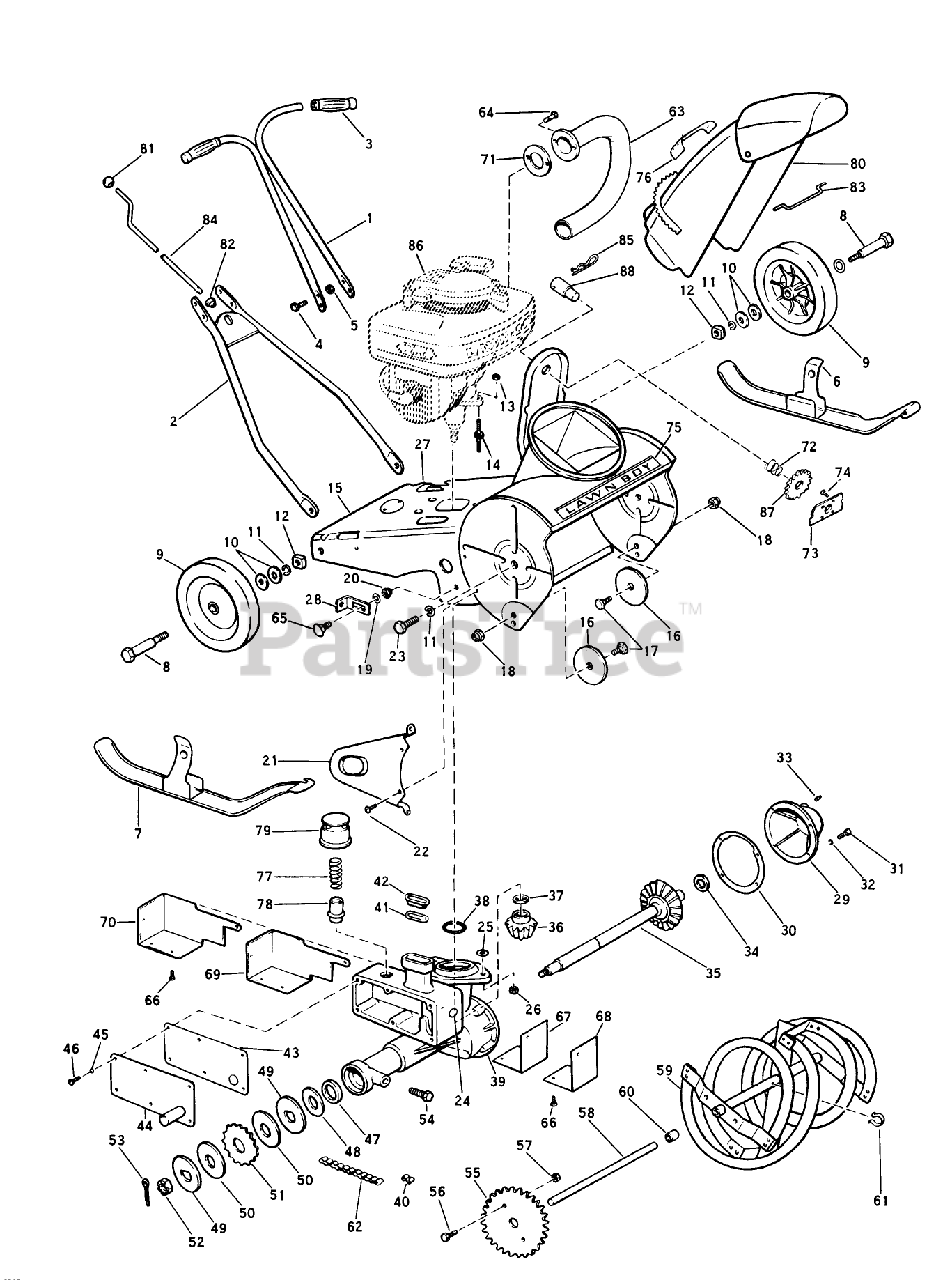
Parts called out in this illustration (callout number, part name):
3	HANDLE GRIP
5	STOP NUT
10	WASHER WROUGHT
11	WASHER, LOCK
15	Base, Housing and Bracket Assy.
17	Stud-Front Wheel
20	Nut-Huglok
24	Plug-Core
25	Washer-G-case to Base Stud
29	Cover-Gearcase
31	Screw-Gearcase Cover
34	Thrust Washer-Driveshaft Gear
35	Driveshaft and Gear Assembly
37	Thrust Washer-Pinion Gear
38	O Ring-G-case to Crankcase
49	Washer-Steel "D" Hole
53	Cotter Pin-Wheel
54	Screw-Stabilizer Bracket
57	Nut-Huglok
74	Drive Screw
75	Decal-"LAWN BOY"
76	Decal-Instruction
88	Stud Shaft-Chute Adj.
